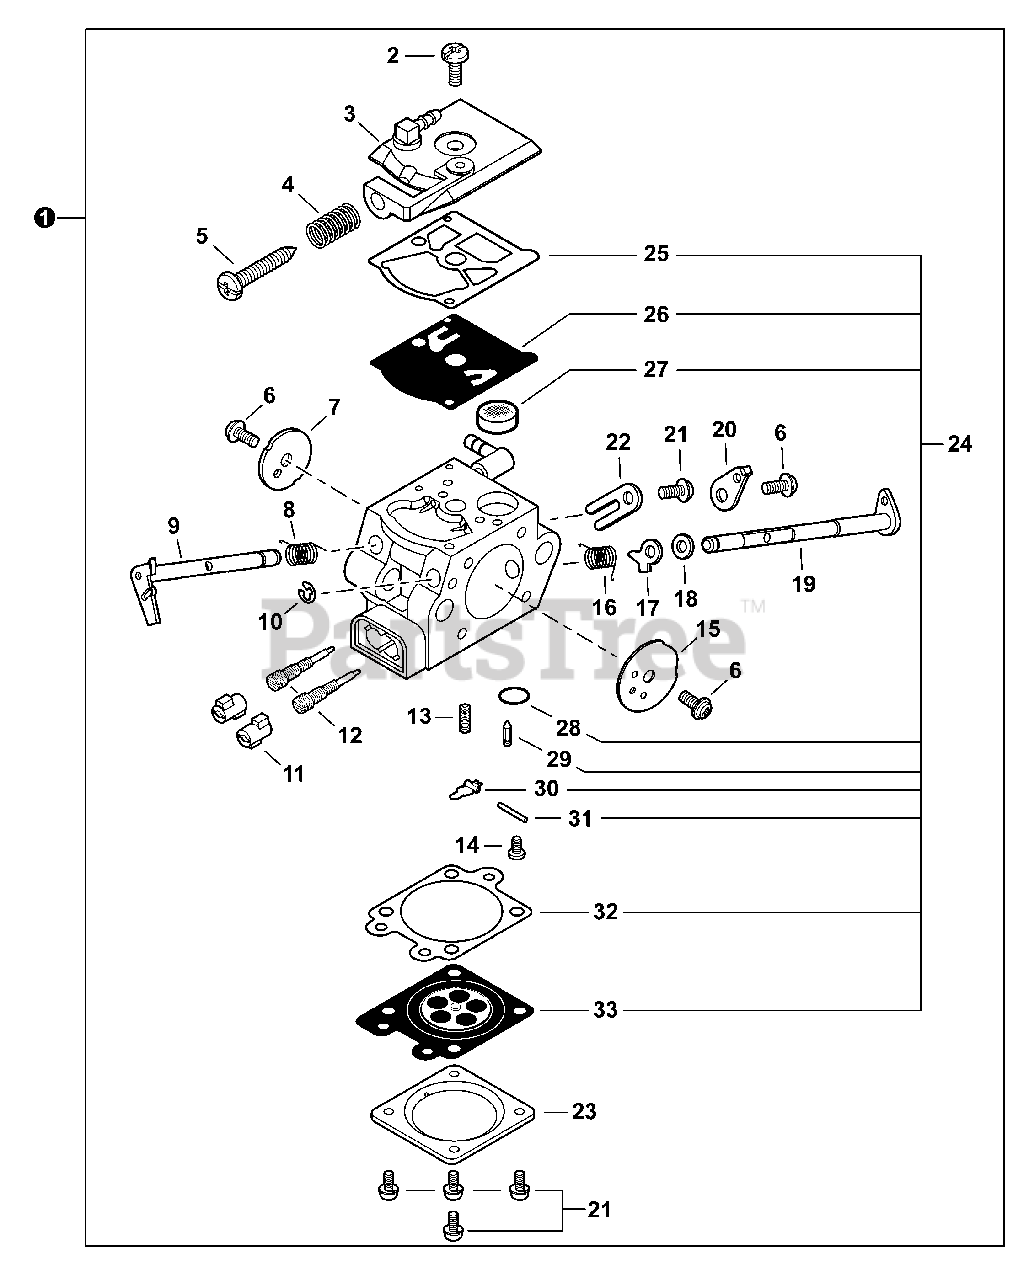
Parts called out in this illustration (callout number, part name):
1	CARBURETOR WT-985
3	COVER, FUEL PUMP
4	SPRING, IDLE ADJUST
5	SCREW, IDLE ADJUST
7	VALVE, THROTTLE
8	SPRING, THROTTLE RETURN
9	SHAFT, THROTTLE
11	CAP, LIMITER
12	NEEDLE, MIXTURE
13	SPRING, METERING LEVER
14	SCREW, METERING LEVER PIN
15	VALVE, CHOKE
16	SPRING, CHOKE RETURN
17	LEVER, FAST IDLE
19	SHAFT, CHOKE
20	LEVER, THROTTLE
22	CLIP, THROTTLE SHAFT
23	COVER, METERING DIAPHRAGM
24	REPAIR KIT, CARBURETOR
25	GASKET, PUMP
26	DIAPHRAGM, PUMP
27	SCREEN, FUEL INLET
28	PLUG, WELCH
29	VALVE, INLET NEEDLE
30	LEVER, METERING
31	PIN, METERING LEVER
32	GASKET, METERING DIAPHRAGM
33	DIAPHRAGM, METERING
